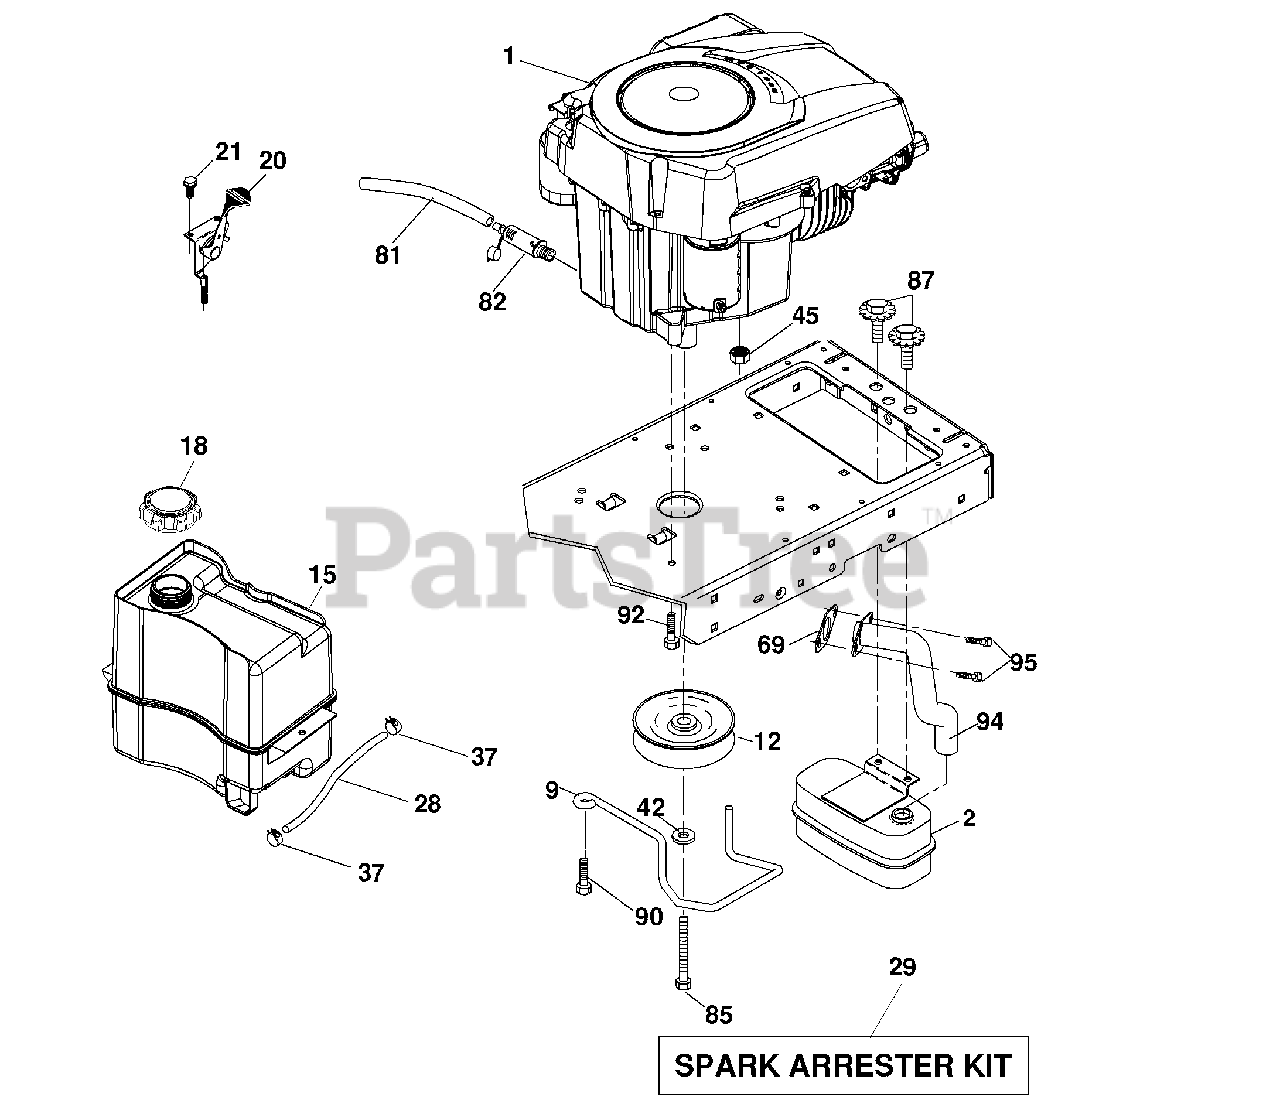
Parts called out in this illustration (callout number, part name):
9	Keeper Belt Engine
12	Pulley Engine
15	Tank Fuel
18	Cap Asm
20	Control Throttle
21	Screw 10 x 3/4 Single Lead Hex
28	Fuel Line
29	Spark Arrester Kit
37	Clamp Hose
42	Washer Lock 7/16
45	Nut Keps Hex 1/4-20 unc
79	Screw Socket Head 5/16-18 x .75
81	Tube Drain Oil Easy
82	Plug Drain Oil
85	Bolt Hex 7/16-20 x 4 x Gr. 5-1.5 Thr
87	Bolt 5/16-18 UNC x 3/4 w/Sems
90	Screw 3/8-16 x 1
92	Screw 3/8-16 x 1
94	Tube Exhaust
95	Screw Socket Hd. 5/16-18 x .75
